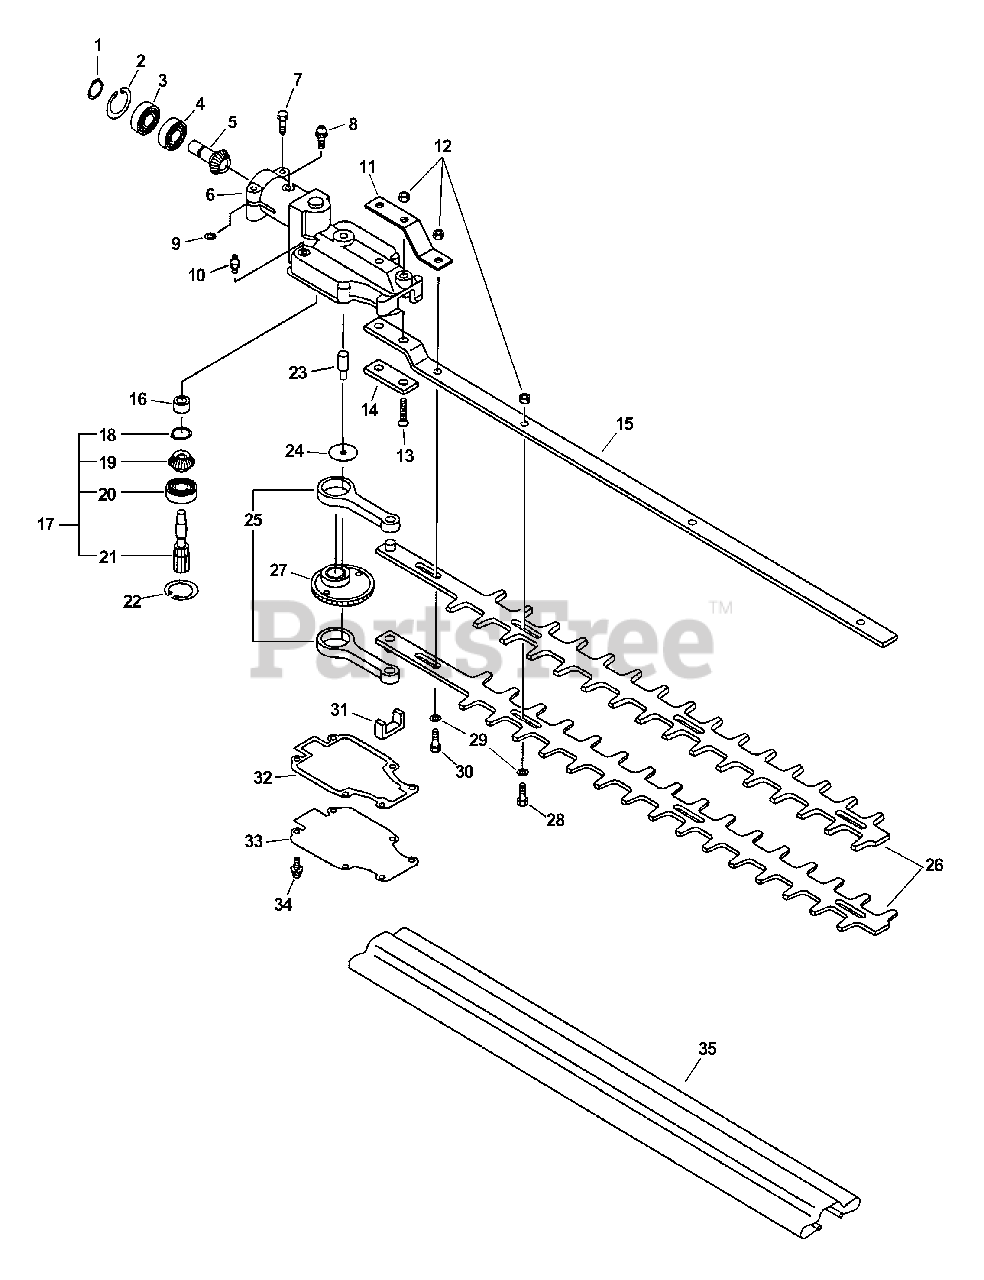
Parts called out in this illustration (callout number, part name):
1	RING, SNAP Ø12
2	RING, RETAINING Ø24
3	BEARING, BALL 6901Z
4	BEARING, BALL 6901
5	GEAR, BEVEL
6	CASE, GEAR
7	BOLT 5×28
8	BOLT 5×12
10	FITTING, GREASE
11	BRACKET
13	SCREW 6×35
14	PLATE, EYE
15	SUPPORT, BLADE 20"
16	BEARING, NEEDLE
17	SPUR GEAR ASSY
18	RING, RETAINING
19	GEAR, BEVEL - DRIVEN
20	BEARING, BALL 6901
21	GEAR, PINION
22	RING, RETAINING Ø24
23	DRIVESHAFT
25	ROD, CONNECTING
26	BLADE - 20"
28	BOLT, CUTTER
29	WASHER 6.5×15.5×0.6
30	BOLT 6×20
32	GASKET, GEAR CASE
33	LID, GEAR CASE
34	BOLT 4×12
35	COVER, BLADE
